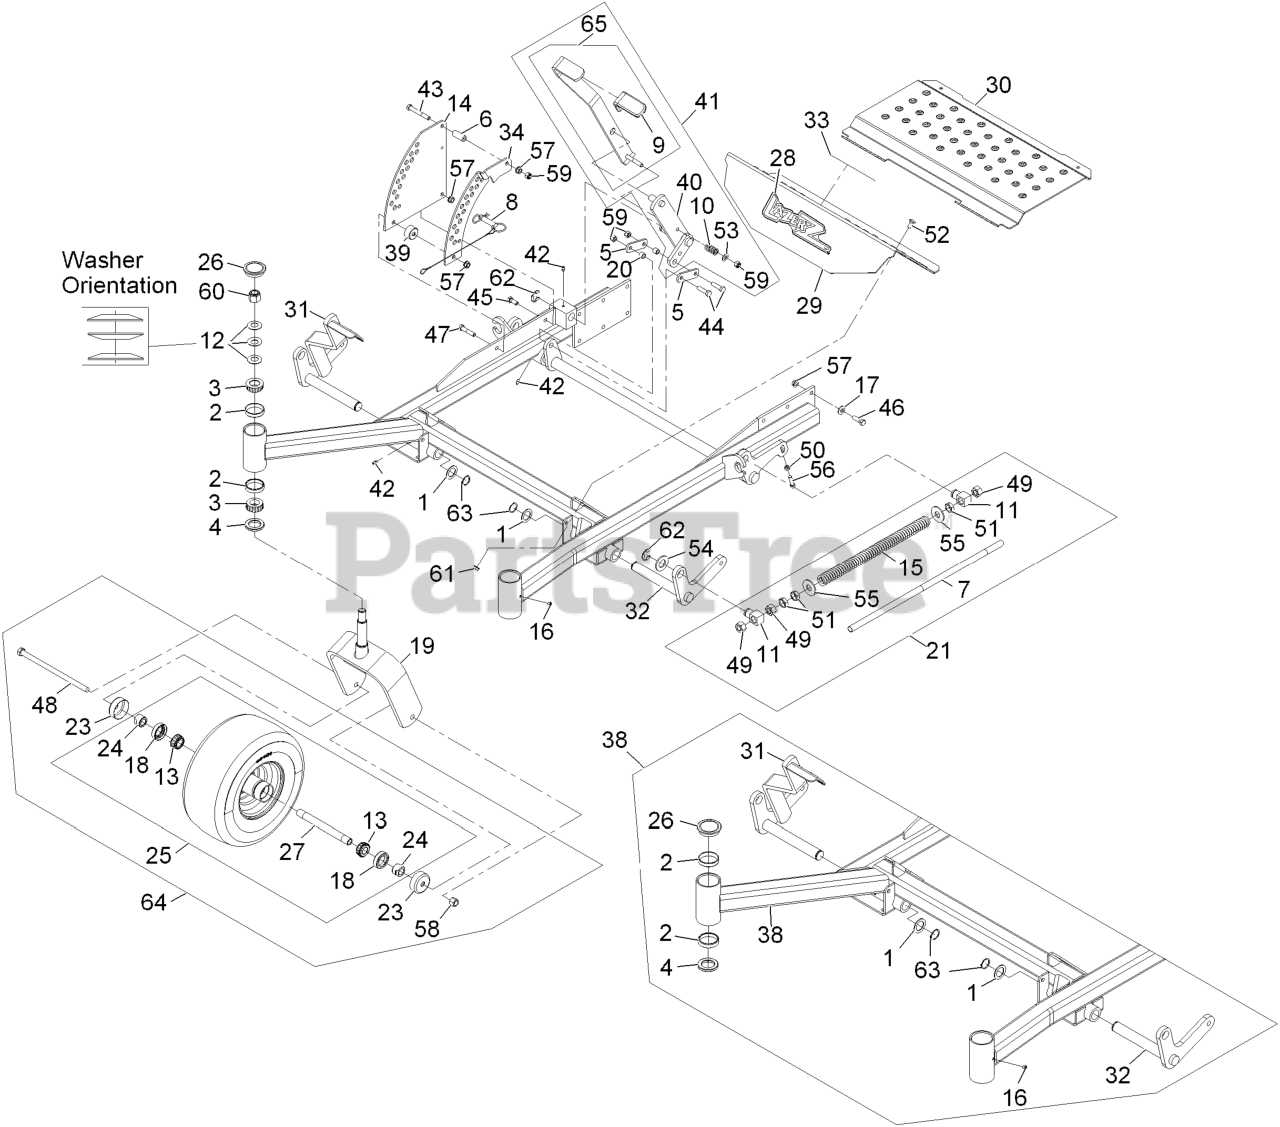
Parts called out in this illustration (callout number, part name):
1	WASHER-SPACER
2	CUP-BEARING
3	Cone-Bearing Tapered Roller
4	SEAL-GREASE
5	ARM-LIFT, DECK
6	BUSHING-LEVER, LIFT
7	ROD-LIFT, DECK
8	PIN-HITCH (W/LANYARD)
9	GRIP-LEVER, LIFT
10	SPRING-COMPRESSION
11	SWIVEL-DECK MOUNT, REAR
12	WASHER-BELLVILLE
13	BEARING-CONE, TAPERED ROLLER
14	PLATE-LIFT, DECK
15	SPRING,DECK SUPPORT
17	WASHER-BELLEVILLE
18	SEAL-CASTER
20	BUSHING
21	ASM,FRONT FRAME SPRING
23	GUARD-SEAL
24	SPACER-NUT
26	CAP-GREASE
28	DECAL,LAZER MODEL
29	ASM, FLOORPAN FRONT W/DEC
30	Floorpan, Lift Out
31	WLD,FRONT LIFT W/LEVER
32	WLD,FRONT LIFT SHAFT-LH
33	DECAL-SLOPE
38	ASM, FRONT FRAME 72"
40	WLD,ARM DECK LIFT
41	ASM,Deck Lift Handle
42	FITTING-GREASE
43	SCREW-HH
44	SCREW-HH
45	SCREW-HH
46	SCREW-HH
47	SCREW-HH
48	SCREW-HH
49	NUT-HEX
50	NUT-JAM
51	NUT-JAM
52	BOLT-CARR
53	WASHER-FLAT
54	WASHER-FLAT
55	WASHER-FLAT
56	SCREW-HSH
57	NUT-HHF, WHIZ
58	NUT-LOCK, NI
59	NUT-LOCK, NI
60	NUT-LOCK, NI
62	RING-RETAINING, EXT
63	RING-RETAINING
64	WHEEL & TIRE ASM
65	LIFT LEVER/GRIP ASM
